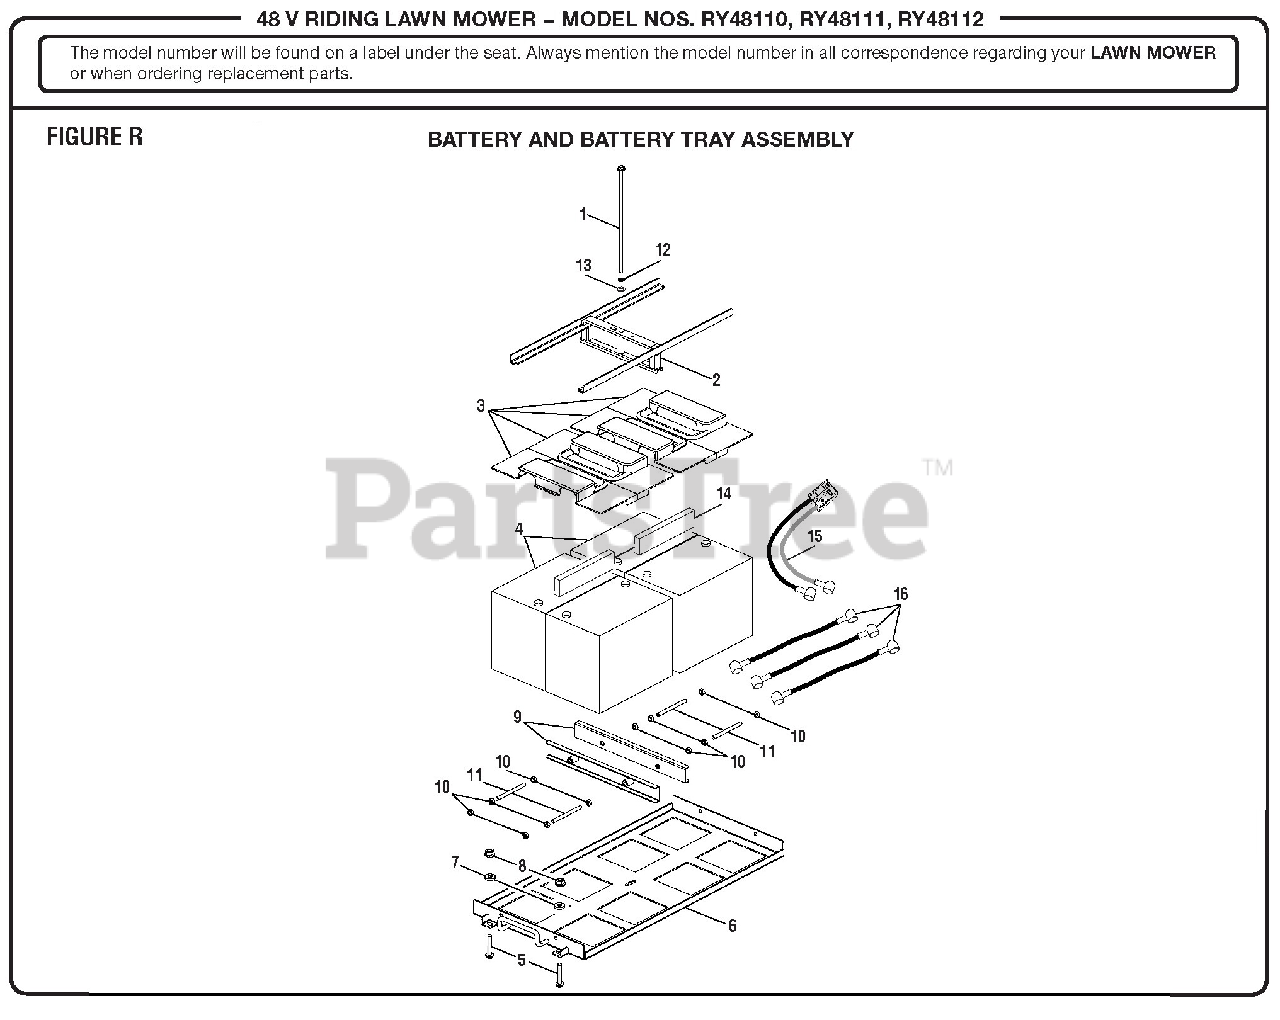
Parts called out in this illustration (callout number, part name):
1	Bolt (M8)
2	Battery Tie Down
3	Battery Cover
4	Battery (LPC12-75, RY48110, RY48112)
5	Flange Bolt (M8 x 55 mm, Hex Hd.)
6	Battery Tray
7	Metal Bushing
8	Flange Nut (M8)
9	Battery Holder Bracket
10	Hex Nut (M8)
11	Threaded Rod (M8 x 100 mm)
12	Lock Washer (OD9.8 x ID8.5 x 5t)
13	Washer (OD12.5 x ID8.4 x 4t)
14	Battery Spacer (LPC12-75)
15	Two Wire Battery Cable (4 AWG Black & 4 AWG Red, 250 mm)
16	Battery Cable w/Covers (Red and Black, 120 mm)
